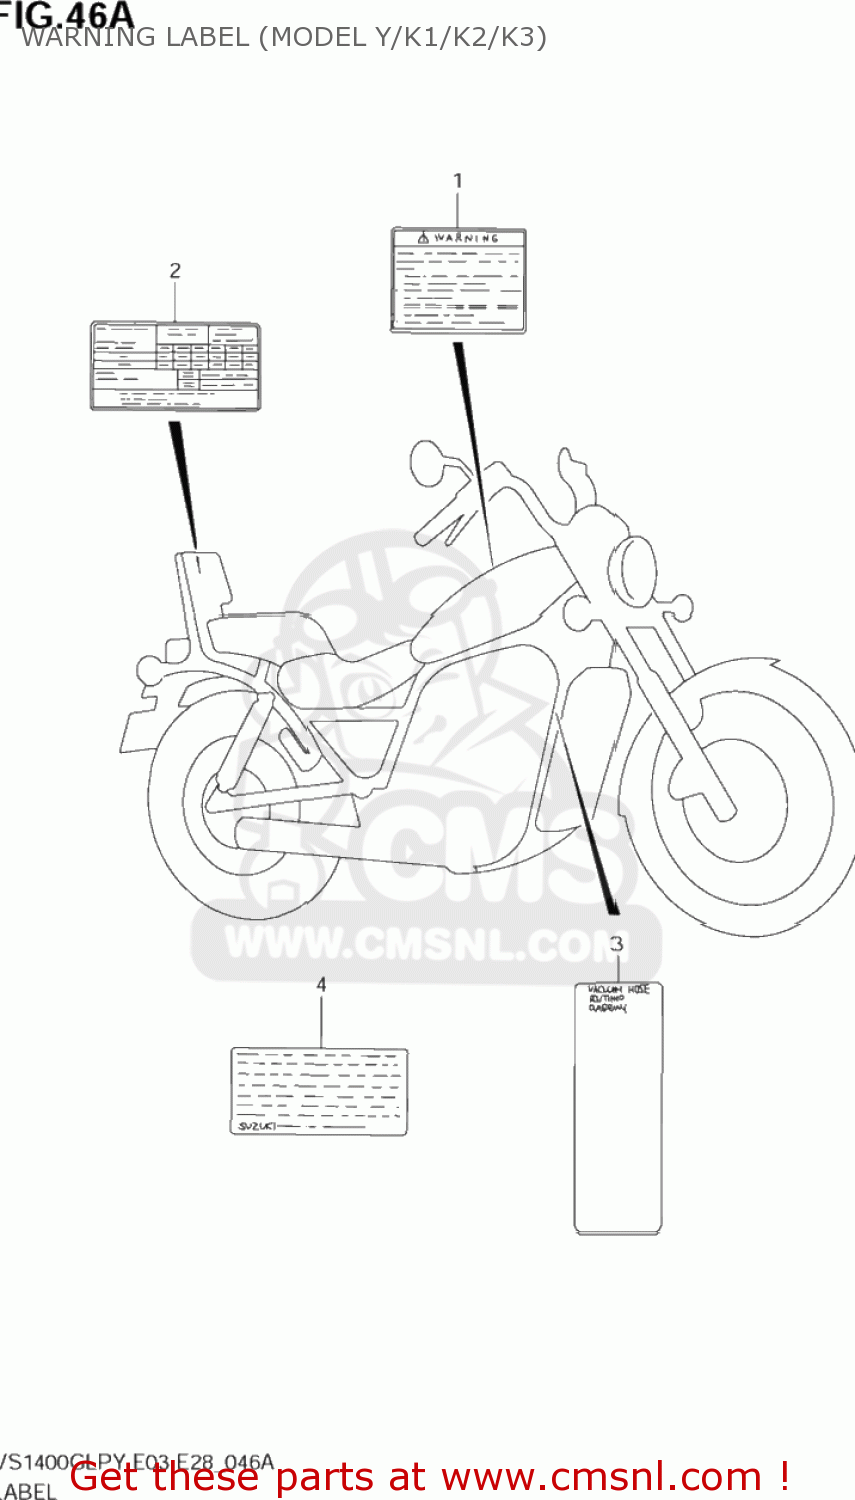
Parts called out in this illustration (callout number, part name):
1	LABEL,GENERAL WARNING
2	LABEL,TIRE INFORMATION
3	LABEL,VACUUM HOSE ROUTING
4	LABEL,MANUAL NOTICE
5	MANUAL,OWNER'S
